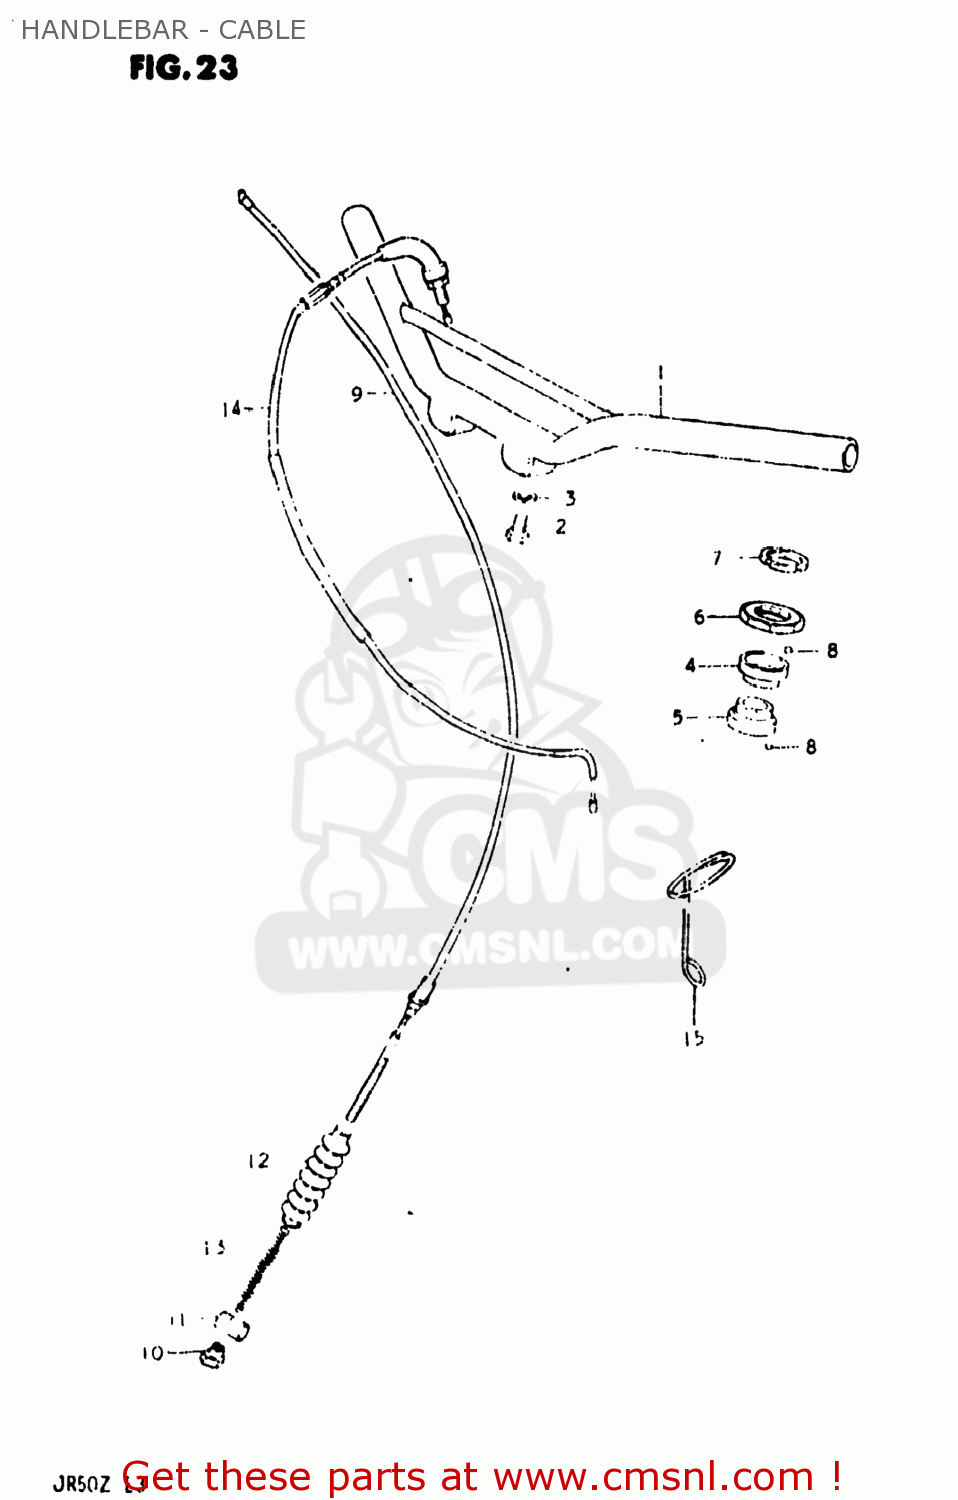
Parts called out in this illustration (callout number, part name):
1	HANDLEBAR
2	BOLT
3	LOCK WASHER
4	RACE,STEERING,INNER,UPPER
5	RACE,STEERING,INNER,LOWER
6	RACE,STEERING,OUTER,UPPER
7	NUT,STEERING STEM
8	BALL
9	CABLE ASSEMBLY,FRONT BRAKE
10	NUT
11	PIN,10X19
12	SEAL,DUST(7X16X75)
13	SPRING
14	CABLE ASSEMBLY,THROTTLE
15	CLIP
